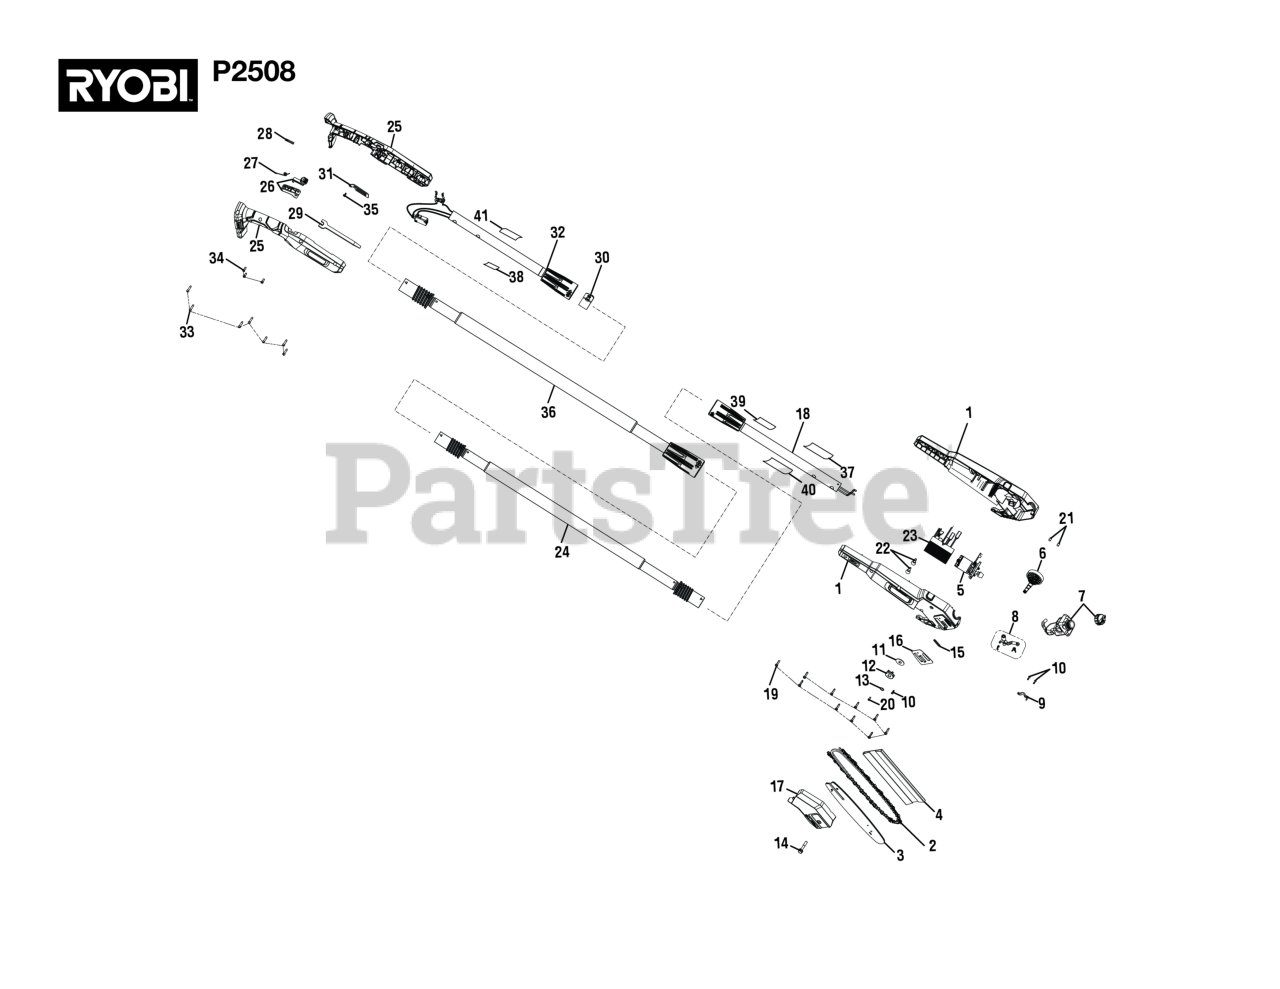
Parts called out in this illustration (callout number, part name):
1	Housing Assembly
2	8 in. Saw Chain
3	Guide Bar
5	Motor Assembly
6	Output Shaft Assembly
7	Oil Tank And Cap Assembly
9	Pump Clamp
10	Screw (M3 x 10 mm)
11	Cover Plate (Internal "D" Washer)
13	Retaining Ring
14	Screw with Spring Washer (M6 x 35 mm)
15	Oil Outlet Seal Ring
16	Guide Bar Plate
17	Sprocket Cover Assembly
18	Upper Pole Assembly
19	Screw (M4 x 18 mm, T20 Torx Pan Hd.)
20	Screw (M4 x 16 mm)
21	RUBBERSEAL
22	Wire Connector (Closed End)
23	Motor Controller
24	Mandatory Boom Assembly
25	Handle Assembly
26	Trigger And Lock Off Assembly
27	Trigger Spring
28	Compression Spring (Trigger Lock)
30	Clamp Assembly
31	Strap Hanger
32	Lower Pole Assembly
33	Screw (M4 x 18 mm, T20 Torx Pan Hd.)
34	Screw (M4 x 11 mm, T20 Torx Pan Hd.)
35	Screw (M3 x 8 mm)
36	Middle Pole Assembly
37	Warnings Label (Spanish / French)
39	Data Label
40	Whisper Logo Label
41	Danger Icon Warning Label
